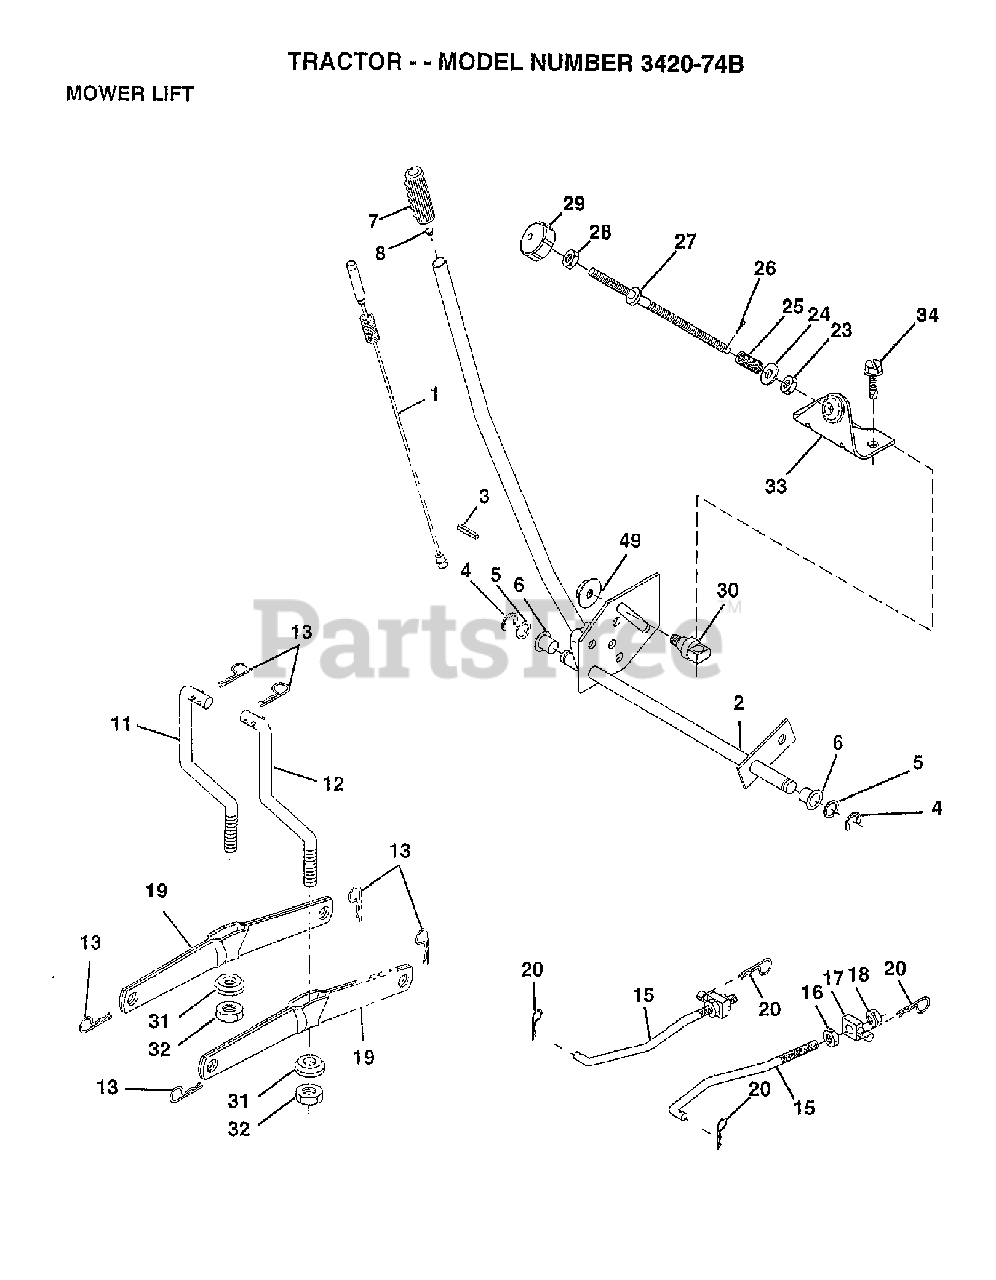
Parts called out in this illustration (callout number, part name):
1	WIRE ASM INNER W/ PLUNGER LT
3	PIN GROOVE
4	RETAINING RING LT
6	BEARING.NYLON
7	GRIP
8	PLUNGER BUT KIT
10	SPRING, COMP T
11	LINK LIFT LH
12	Lift Link Assembly, RH
13	RETAINER SPRING
15	FRONT LINK
16	NUT.HEX.JAM.1/2-13
18	NUT.LK.W/WSH.1/2.
19	ARM.REAR.SUSPENSION
20	SPRING RETAINER
24	WASHER
25	SPRING.COMP.INF.H
27	ROD.LIFT.ADJUSTABLE
28	NUT
29	KNOB INF 3/8-16
30	TRUNNION
32	NUT CROWNLOCK 3/8-24
49	Flange Hex Lock Nut, 3/8-16
50	NUT PUSH M
